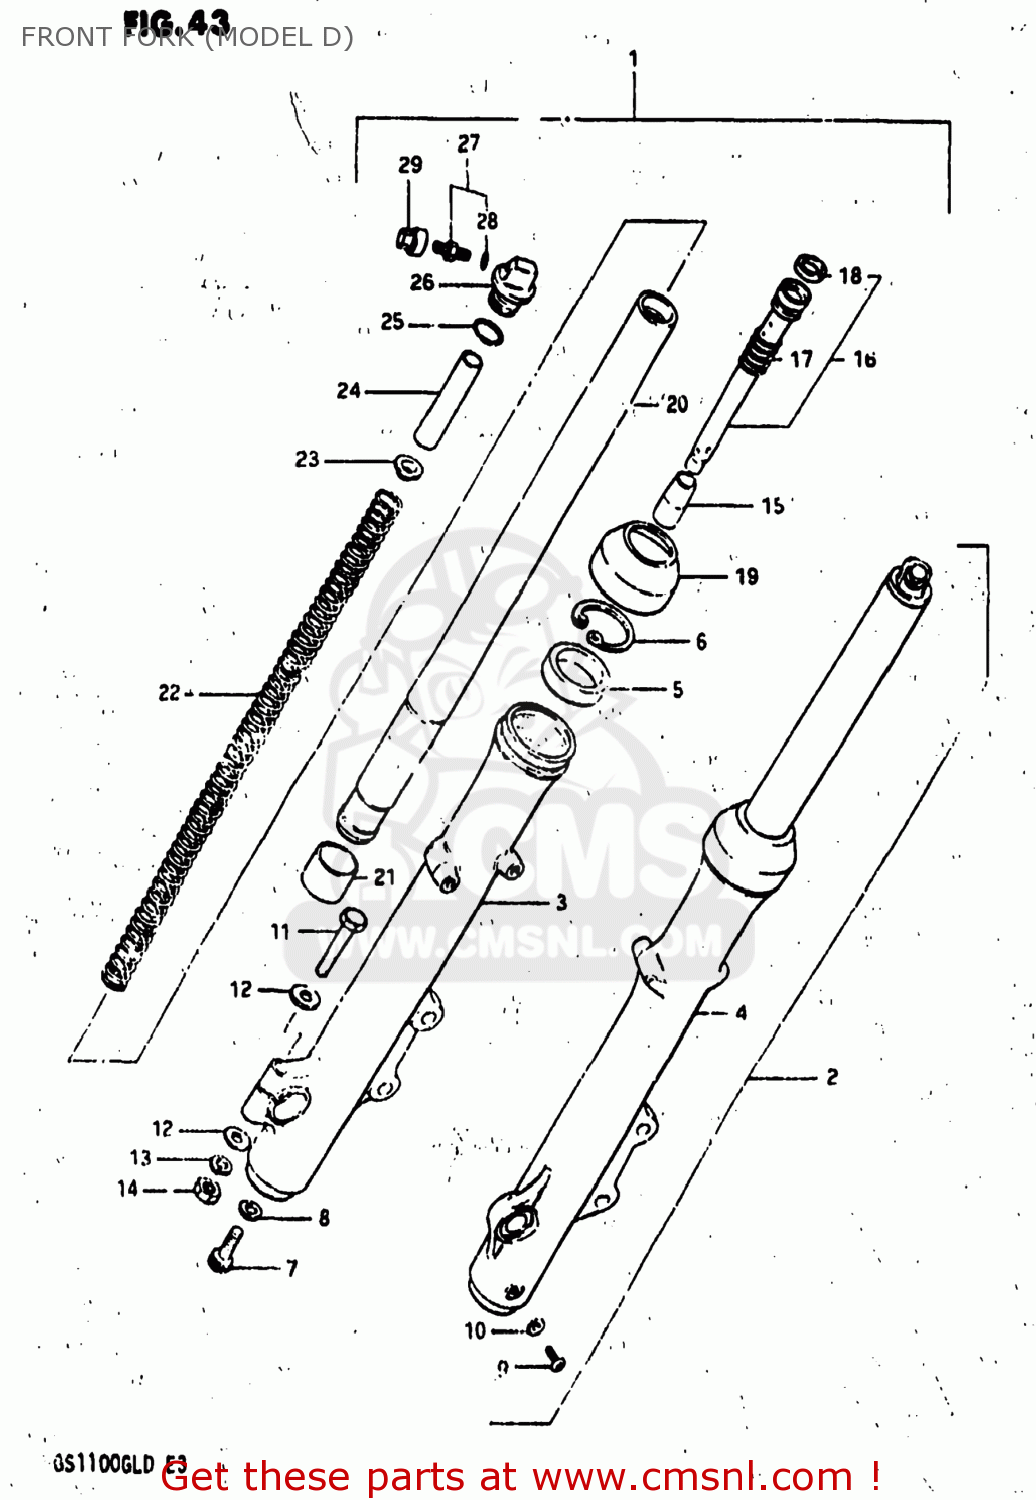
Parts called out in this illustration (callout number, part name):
1	DAMPER ASSEMBLY,RIGHT
2	DAMPER ASSEMBLY,LEFT
3	TUBE,FORK,OUTER,RIGHT
4	TUBE,OUTER,LEFT
5	OIL SEAL,FRONT FORK
6	RING,STOPPER
7	BOLT,FORK CYLINDER(10X25)
8	GASKET (NAS)
9	SCREW
10	GASKET,DRAIN,PLUG (NAS)
11	BOLT 8X50
12	WASHER
13	WASHER,LOCK,8.
14	NUT
15	PIECE,OIL LOCK
16	CYLINDER,FRONT FORK
17	SPRING,REBOUND
18	RING,PISTON
19	SEAL,DUST
20	TUBE,INNER
21	PISTON
22	SPRING,FRONT FORK
23	GUIDE,FRONT FORK SPRING C
24	COLLAR,SPRING
25	O RING
26	CAP,FORK INNER TUBE
27	VALVE
28	O RING
29	CAP,VALVE
